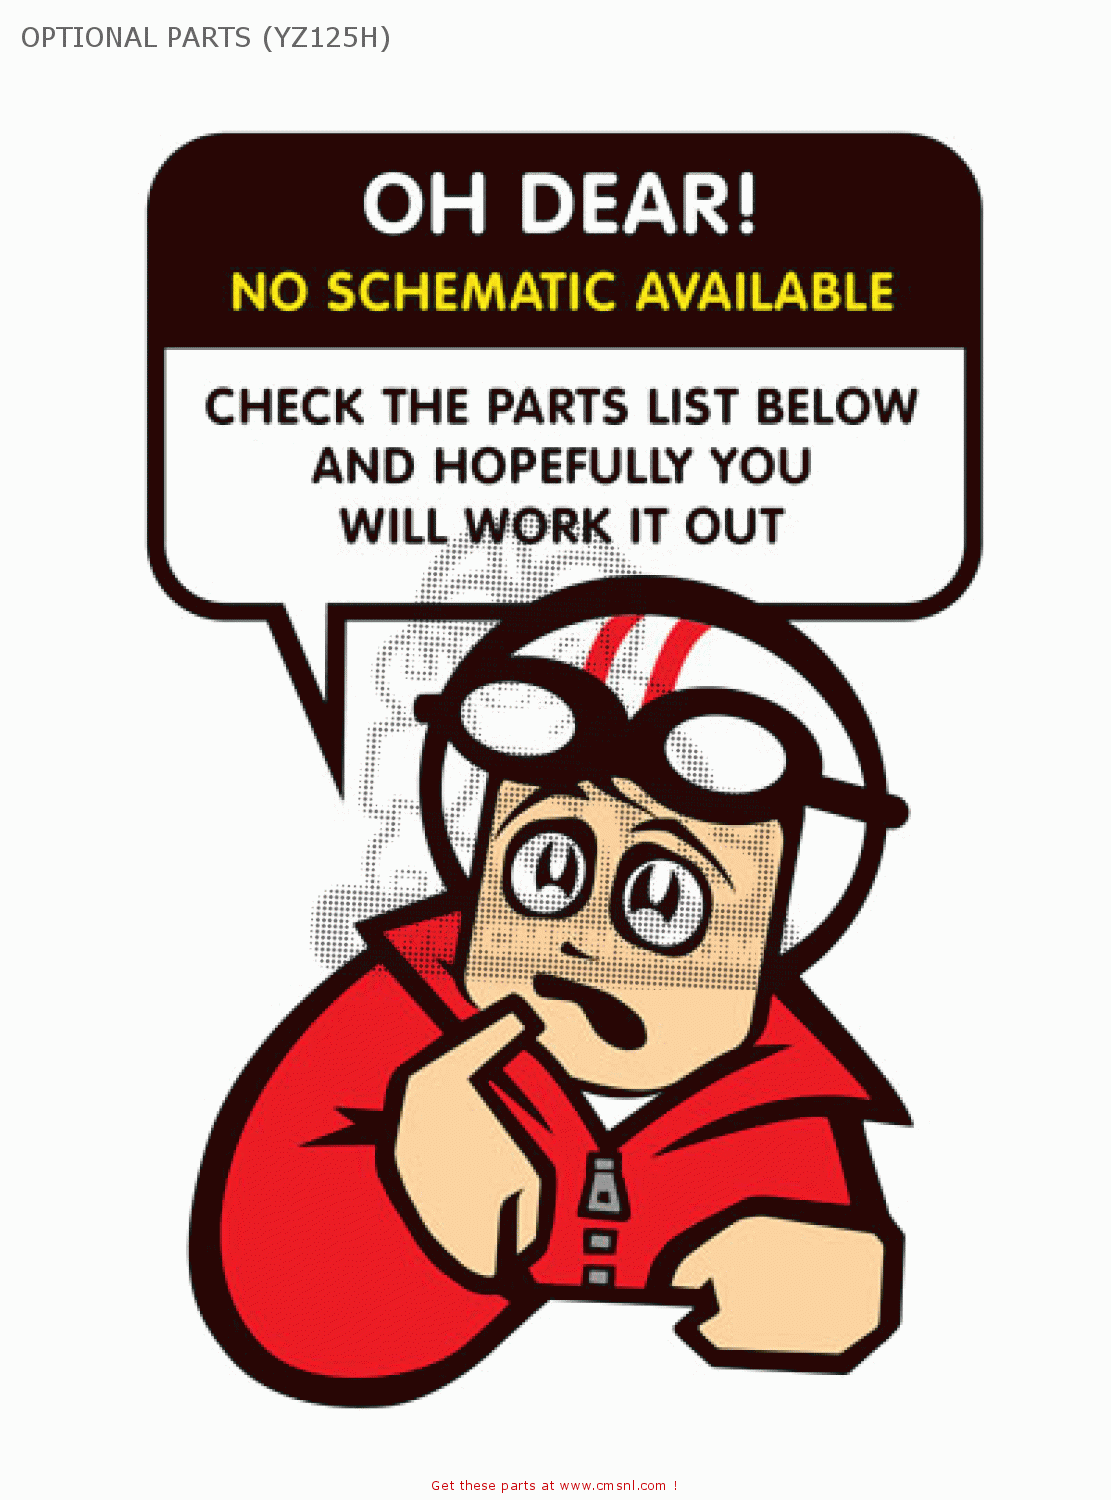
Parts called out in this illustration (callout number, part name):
1	GSKT,CYLNDER (NAS)
2	SEAL,VALVE STEM
3	GASKET,CYLINDER H (NAS)
4	GSKT,HEAD COVER (NAS)
5	GSKT,SIDE COVER (NAS)
7	GASKET,EX.PIPE (NAS)
8	GASKET,PULSE GEN (NAS)
9	GASKET,POINT BASE
10	O-RING,27X2
11	O RING, 5.5X1.5
12	O RING, 30.8M/M
13	O-RING,25X2.4
14	GASKET 7.5 RUBBER
